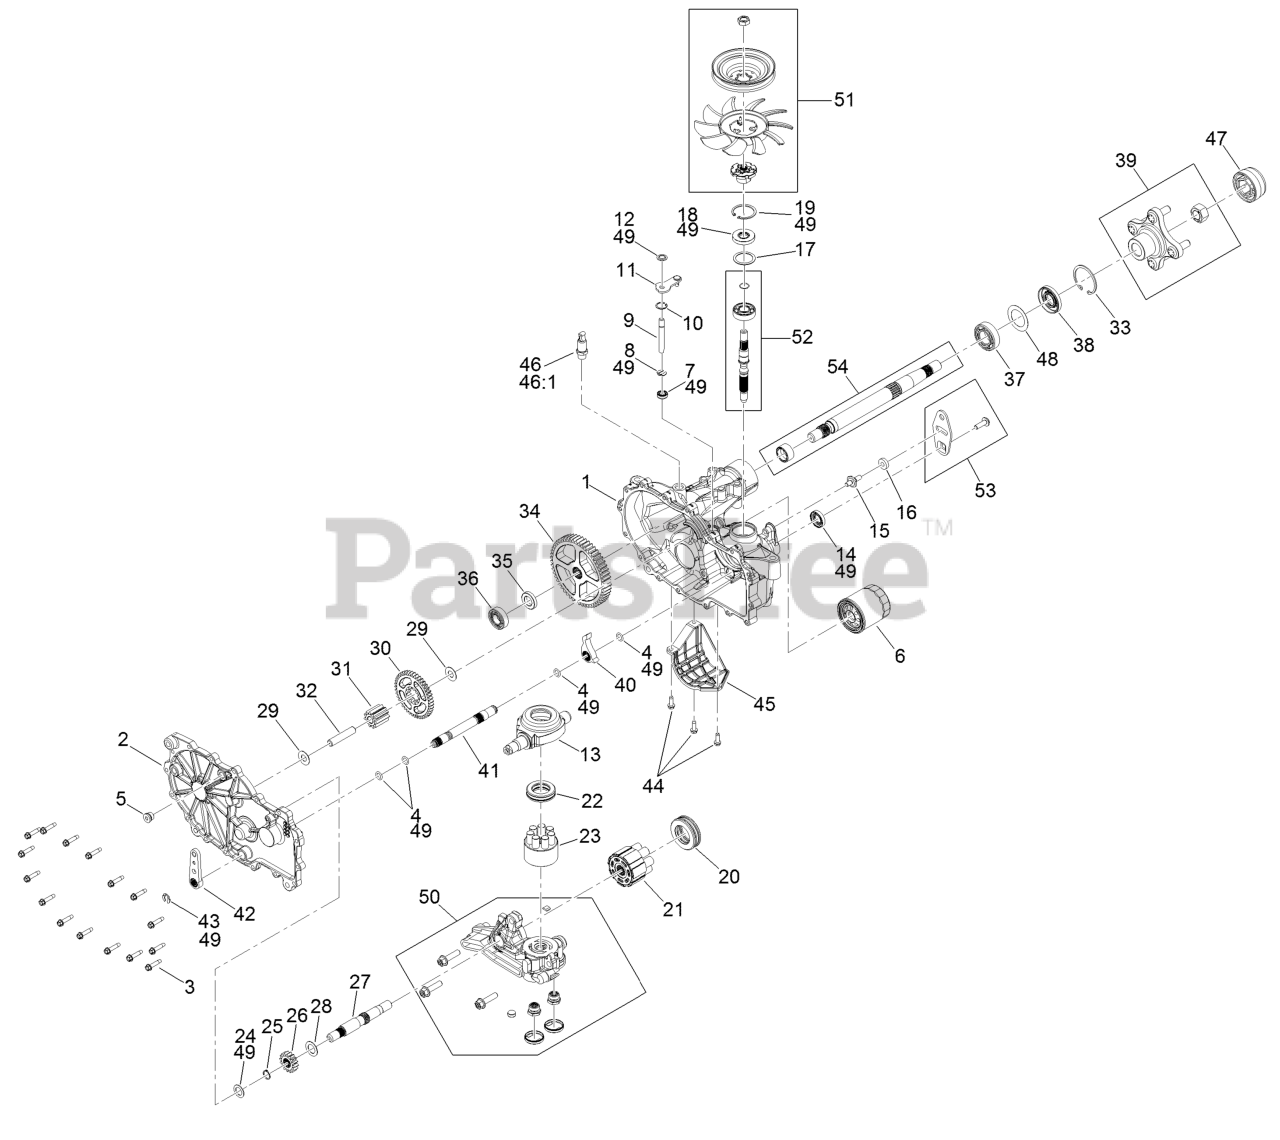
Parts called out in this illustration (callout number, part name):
1	MAIN HOUSING KIT
2	LH SIDE COVER KIT
3	SCREW-HHF
5	PLUG-THREAD, STRAIGHT
6	ELEMENT-OIL FILTER, HYD
7	SEAL-LIP
8	RING-RETAINING, EXTERNAL
9	ROD-BYPASS
10	RING-RETAINING, INTERNAL
11	ARM-BYPASS
12	RING-RETAINING, EXTERNAL
13	SWASHPLATE-TRUNNION
14	SEAL-LIP
16	PUCK-FRICTION
18	SEAL-LIP
19	RING-RETAINING
20	BEARING-THRUST
21	MOTOR CYLINDER BLOCK KIT
22	BEARING-THRUST
23	PUMP BLOCK ASM
24	WASHER-FLAT
25	RING-RETAINING
26	GEAR-16T
27	SHAFT-MOTOR
30	GEAR-43T
31	GEAR-11T
32	PIN-JACKSHAFT
33	RING-RETAINING
34	GEAR-54T
36	BEARING-BALL
37	BEARING-BALL
39	HUB KIT
40	PAWL-BRAKE
41	SHAFT-BRAKE, INBOARD
42	HANDLE-BRAKE
43	RING-RETAINING, EXT
45	GUARD-FILTER, LH
46	ADAPTER-STRAIGHT
46:1	O-RING
47	COVER-NUT, AXLE
49	SEAL KIT
50	CENTER SECTION KIT
51	FAN PULLEY KIT
52	INPUT SHAFT KIT
53	CONTROL ARM KIT
54	AXLE SHAFT KIT
